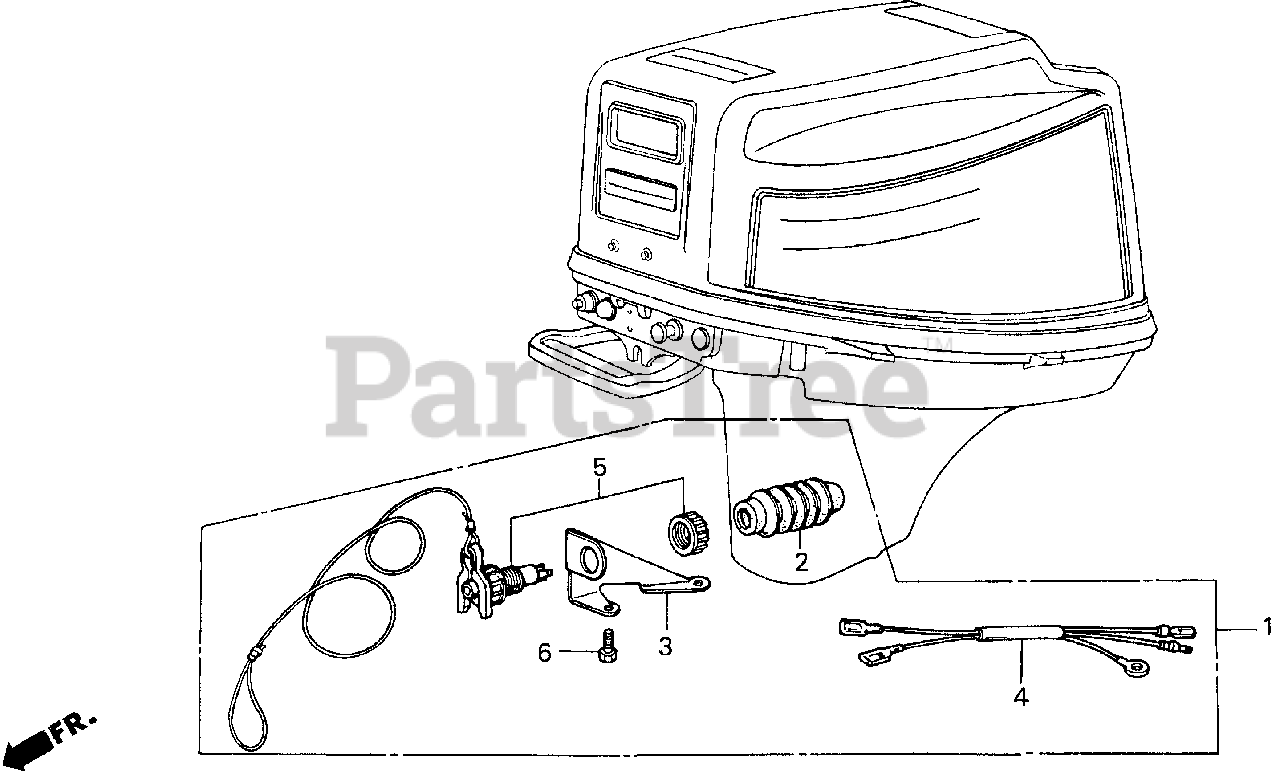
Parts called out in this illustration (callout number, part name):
1	SWITCH KIT, SAFETY
2	RUBBER, SEALING
3	STAY, SAFETY SWITCH
4	WIRE B, SWITCH
5	SWITCH, SAFETY
6	BOLT, HEX. (6X12)
